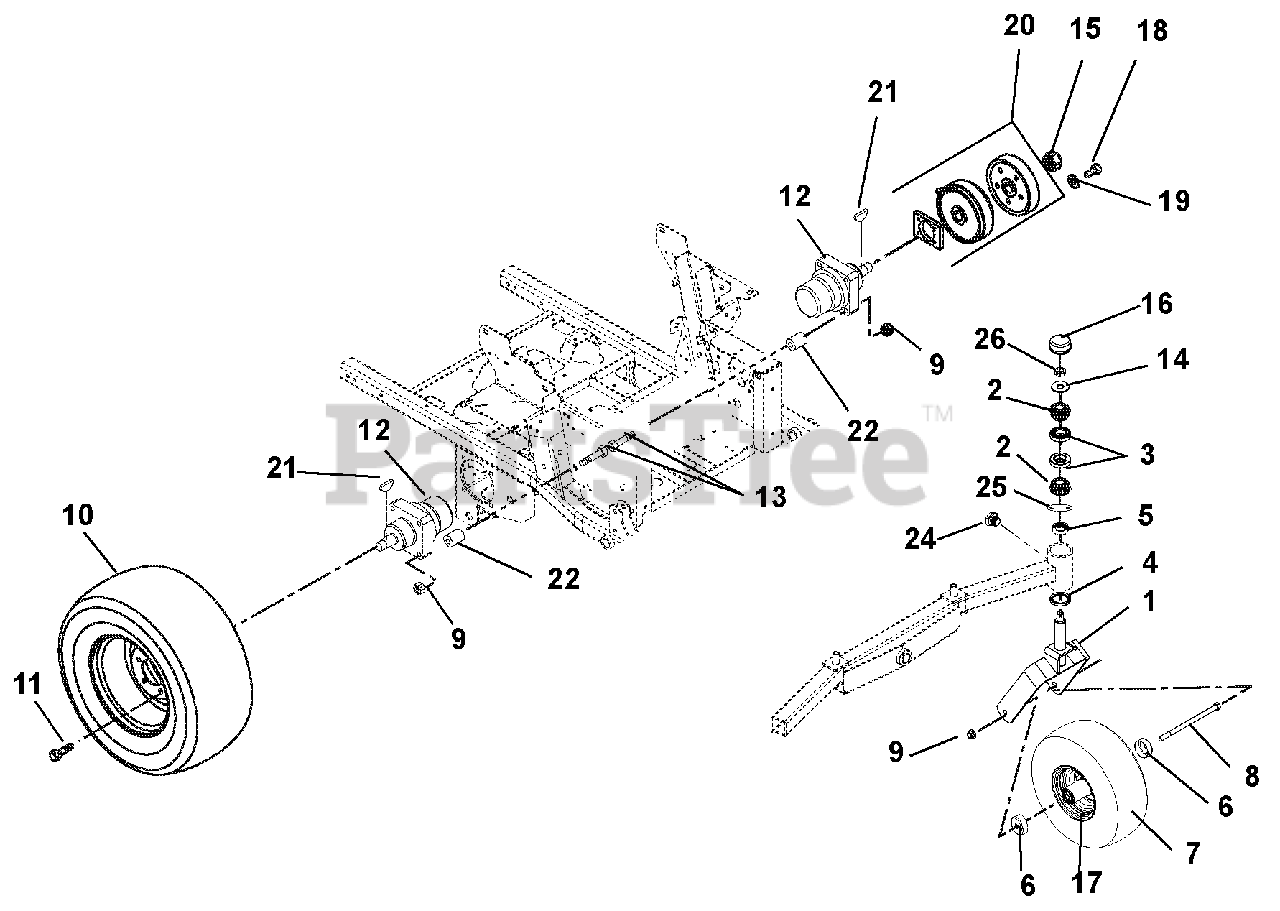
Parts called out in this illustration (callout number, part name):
1	Fork, Front
2	Bearing, Cone
3	Bearing, Cup 2.328 x .465
4	Bearing Seal 1.75 x 2.332 x .312
5	Spacer, Front Caster Fork
6	Shield, Wheel Bearing
7	Wheel/Tire Assembly, 15 x 6-6, Smooth
8	Bolt, Hex .50-13 x 9.00 Grade 5
9	Nut, Locking Top Flange .50-13
10	Tire/Wheel Assembly, 24 x 11.50-12
11	Bolt, Lug .50-20 x 1.38
12	Wheel Motor, Parker
13	Bolt, Wheel Motor .50-13 x 5.00
14	Washer, Flat Steel .812 x 2.00 x .148
15	Nut, Locking Jam Patch 1.00-20
16	Cap, Dust
17	Bearing, Cup 1.78 x .475
18	Bolt, Hex .31-18 x 1.50 Grade 8 EP30
19	Waher, Lock .31 x .078
20	Kit, Parking Brake Service
21	Key, Woodruff .31 x 1.00
22	Bushing, .513 x .748 x 2.129
24	Plug, .250-28 x .185 Hex Head
26	Nut, Jam Center-Lock .75-16
